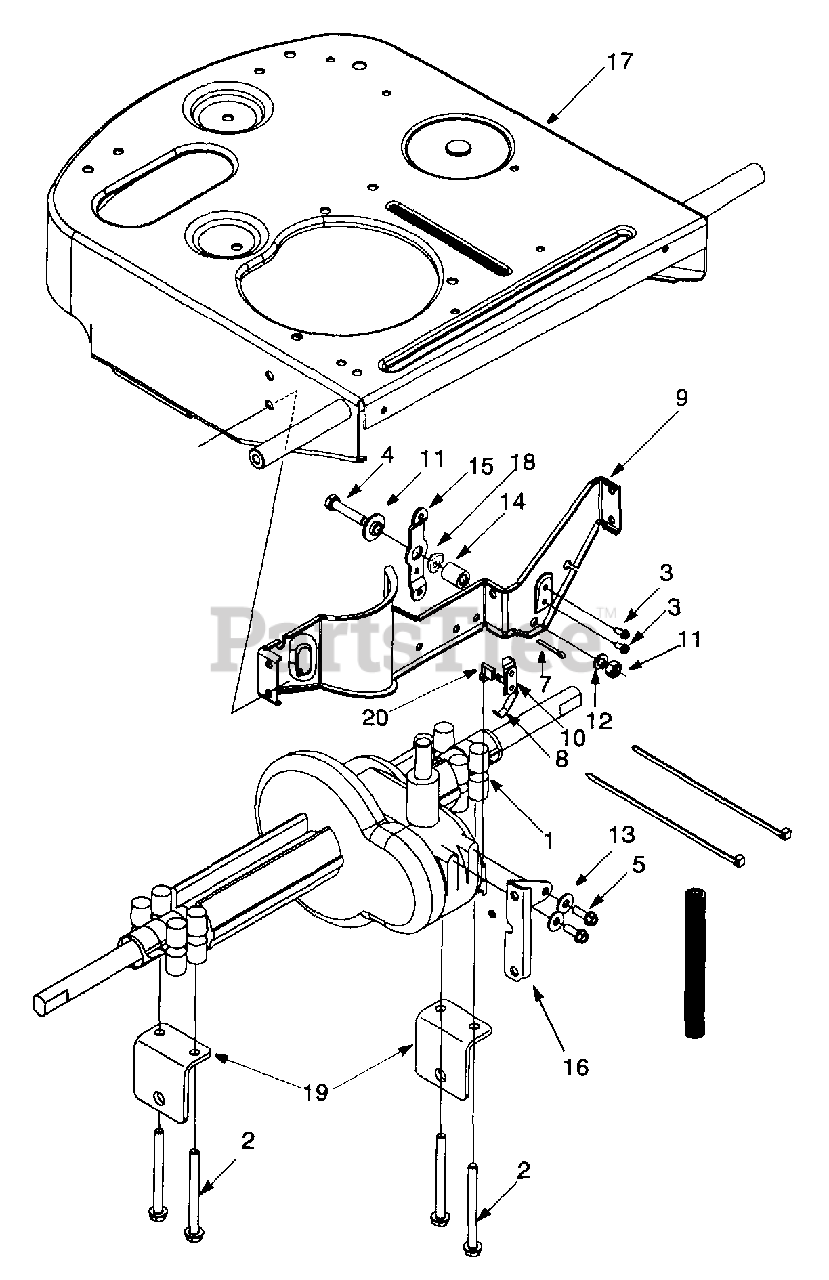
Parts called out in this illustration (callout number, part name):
1	Harness Assembly Adapter
2	Hex TT Screw 5/16-1B x 3.50
3	Hex Washer Head Self-Tap.Screw
4	Hex Screw 5/16-18 x 1.5 Gr.5
5	Thd. Forming Scr. 1/4-20x .75
7	Cotter Pin
8	Insulator Nut Plate
11	Shoulder Bushing
12	Lock Washer 5/16
13	Flat Washer .28 I.D. x .74 0.D. x.083
14	Spacer
15	Shift Lever
